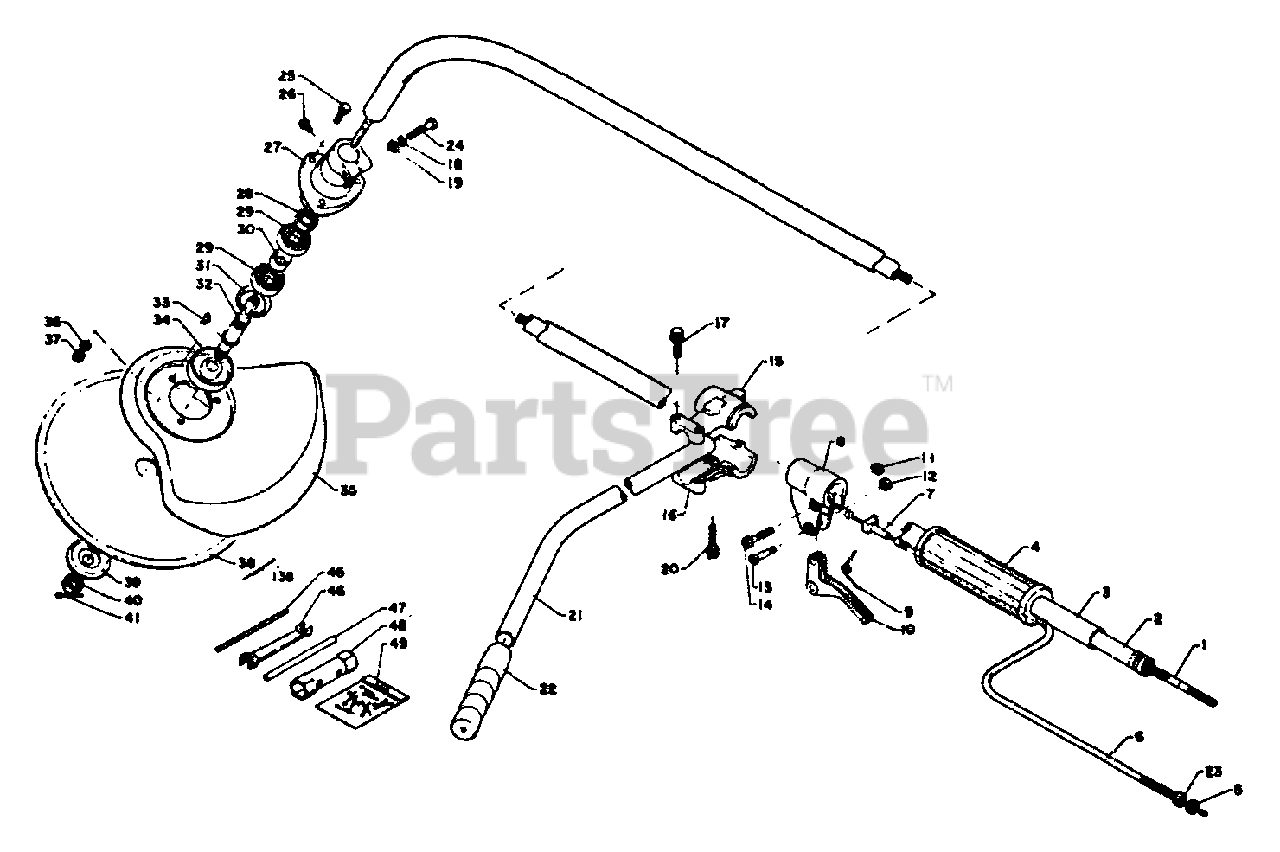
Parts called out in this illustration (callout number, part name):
1	DRIVESHAFT
2	BUSHING
3	PIPE, MAIN
6	CABLE, THROTTLE
7	GUIDE, CABLE
8	BRACKET, TRIGGER
9	SPRING, THROTTLE
10	TRIGGER, THROTTLE
11	NUT M5
12	LOCKNUT - 5
14	SCREW 5×28
15	BRACKET, HANDLE
16	BRACKET, HANDLE
17	BOLT - 5×25
18	WASHER, SPRING 5
19	WASHER, FLAT 5.5×10×0.8
20	BOLT - 5×28
21	HANDLE
23	LOCKNUT
24	BOLT - 5×25
25	SCREW 4×18
26	SCREW 4×10
27	CASE, GEAR
28	NUT
29	BEARING, BALL 6001 DDU
31	RING, SNAP 28
32	DRIVESHAFT
34	PLATE, ADAPTER - UPPER
35	SAFETY GUARD
36	WASHER, SPRING 4 MM
37	NUT M4
38	BLADE - 8 TOOTH
39	PLATE, ADAPTER - LOWER
40	NUT 10
41	PIN, COTTER 2×22
45	TOOL, LOCKING 5×120 MM
46	SPANNER 8×10
47	ROD, HANDLE
48	WRENCH 17×19
49	PIN, COTTER 2×22 (PKG. OF 10)
138	SAW, CIRCULAR
